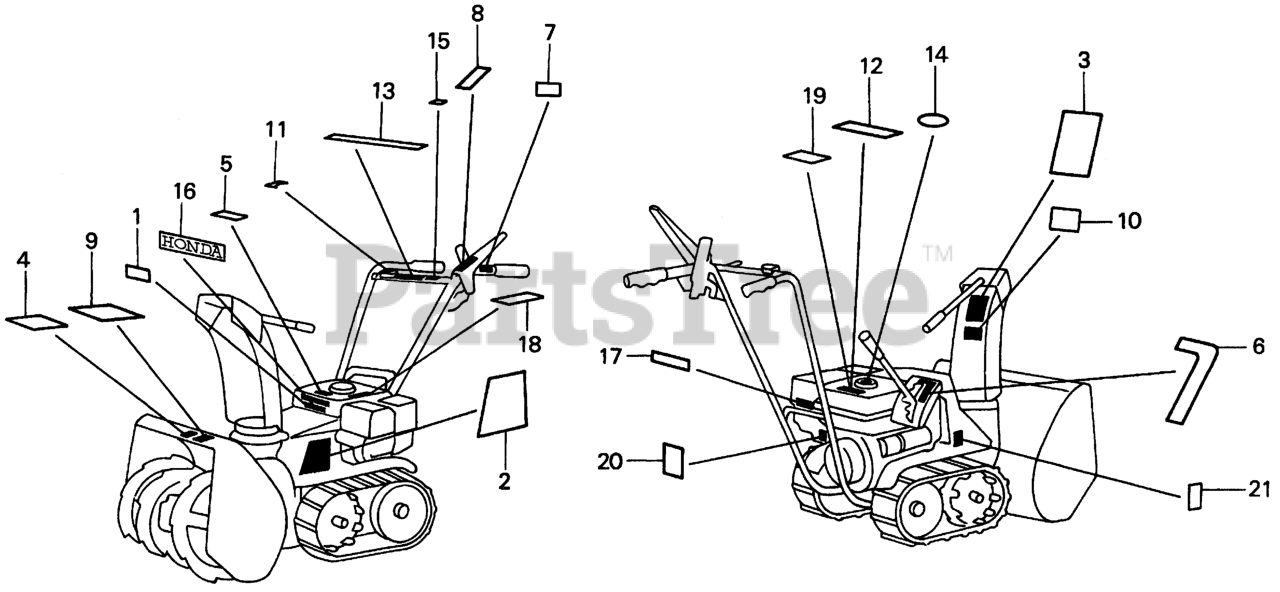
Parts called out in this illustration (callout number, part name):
1	EMBLEM, FUEL TANK
2	EMBLEM, MAIN
3	LABEL, WARNING (ENGLISH)
5	LABEL, WARNING FUEL (A)
6	LABEL, CHANGE INDICATION
8	MARK, CLUTCH
9	MARK, HOUSING DANGER (ENGLISH)
10	MARK, DISCHARGE DANGER (ENGLISH)
11	LABEL, ENGINE SWITCH
12	LABEL, STARTER OPERATION
13	LABEL, OPERATION
14	MARK, CAUTION (EXTERNAL)
15	LABEL, CHOKE
17	MARK, THROTTLE INDICATION
20	MARK, FUEL INDICATION (A)
21	MARK, OIL CAUTION (ENGLISH)
